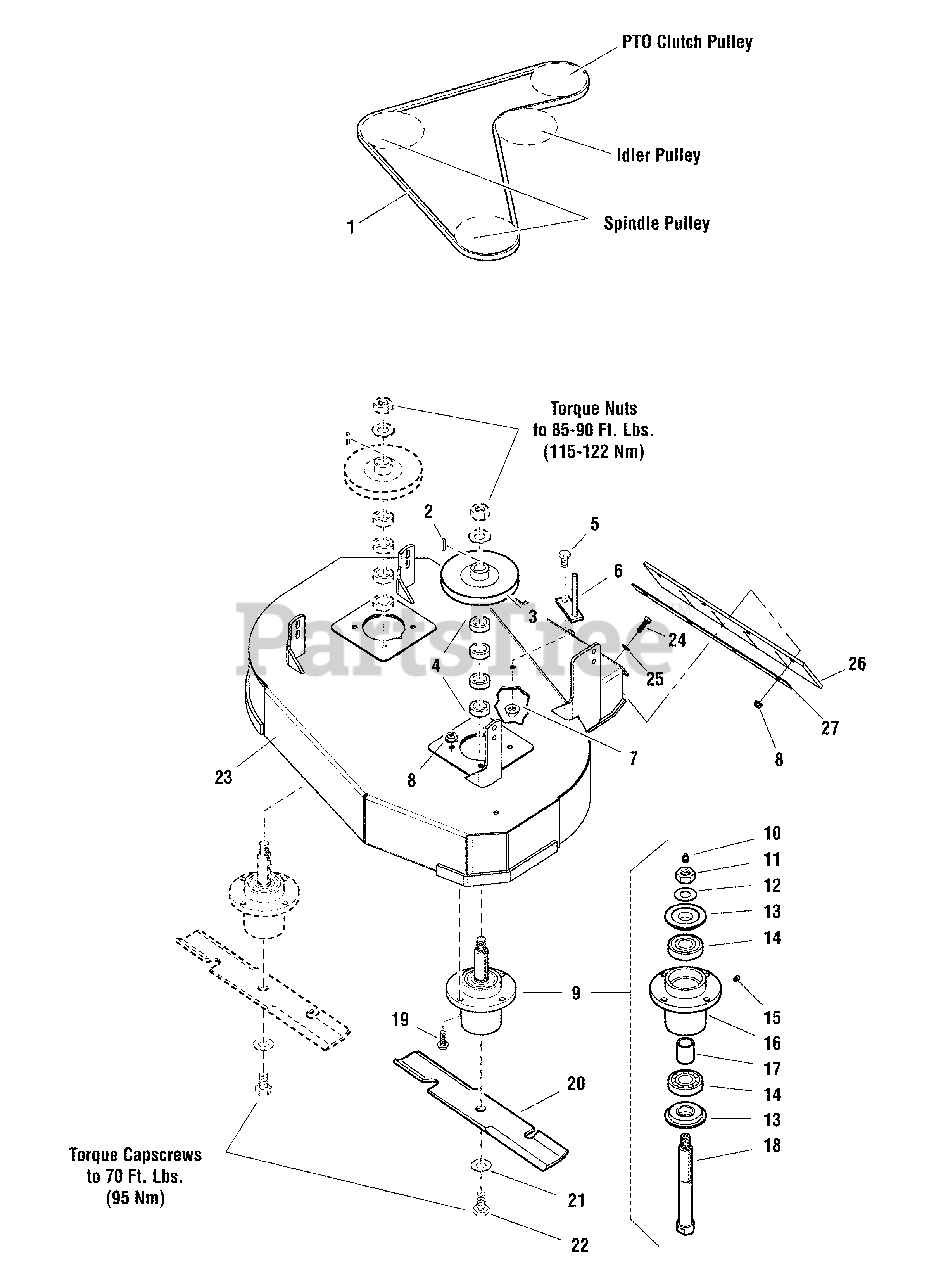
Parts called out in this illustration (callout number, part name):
1	BELT, HA-SEC, 70.40EL, ARAMID, WRPD
2	Key, 1/4" Sq. x 1"
3	PULLEY, SPINDLE
4	SPACER, 1.02 x 1.56 x .50
5	BOLT, 3/8-16 X 1" GD5 CZ
6	BELT GUIDE
7	NUT, Hex, Serrated Flange, 1/4-20
8	NUT, 5/16-18 HEX NYLOCK FLANGE NUT
9	SPINDLE ASSEMBLY, Complete
10	FITTING, 1/8 NPT STR, SHORT
11	NUT, 3/4-16 Hex
12	WASHER, 3/4 BELLEVILLE CL/ZC
13	TRASH SHIELD
14	BEARING, .98 X 2.44 X .67
15	FITTING, RELIEF, 1-5 PSI
16	HOUSING, SPINDLE
17	SPACER, 1.00 X 1.25 X 1.75
18	SHAFT, SPINDLE
19	BOLT, Flange Head, 5/16-18 x 1-1/4
20	MOWER BLADE, 16-1/4"
21	WASHER, 5/8" USS
22	BOLT, 5/8-11 X 1-3/4 GD8
23	DECK SHELL W/ DECALS (5405152B)
24	BOLT, 5/16-18 X 1" GRD5 YZ
25	WASHER, 5/16" SAE
26	FLAP, RUBBER, 32RD
27	PLATE, RETAINING, 32RD - RED
